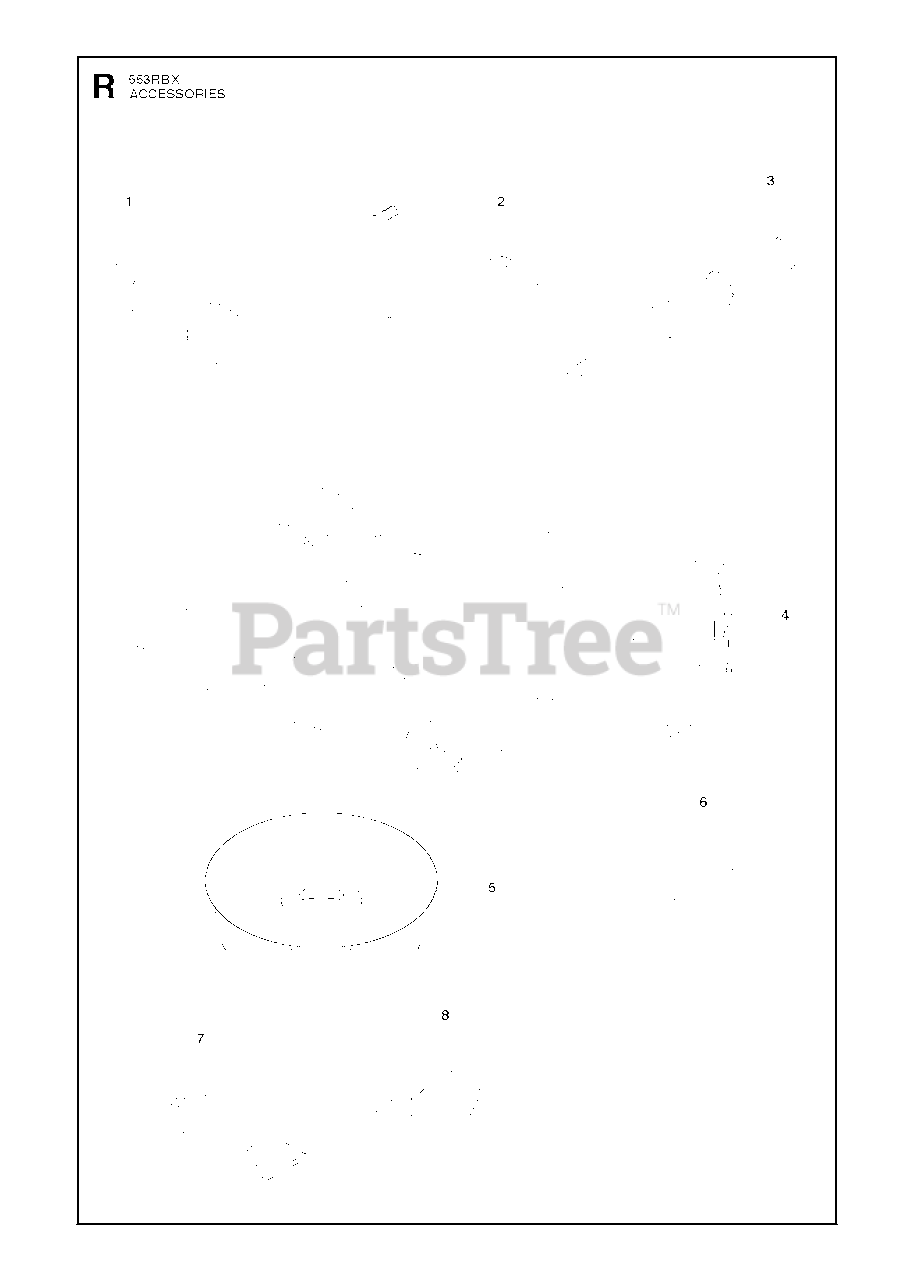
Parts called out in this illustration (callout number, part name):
3	SCREWDRIVER
4	TRANSPORT GUARD
6	Air Filter Oil, HVA 1L Bottle
7	BEVEL GEAR GREASE
